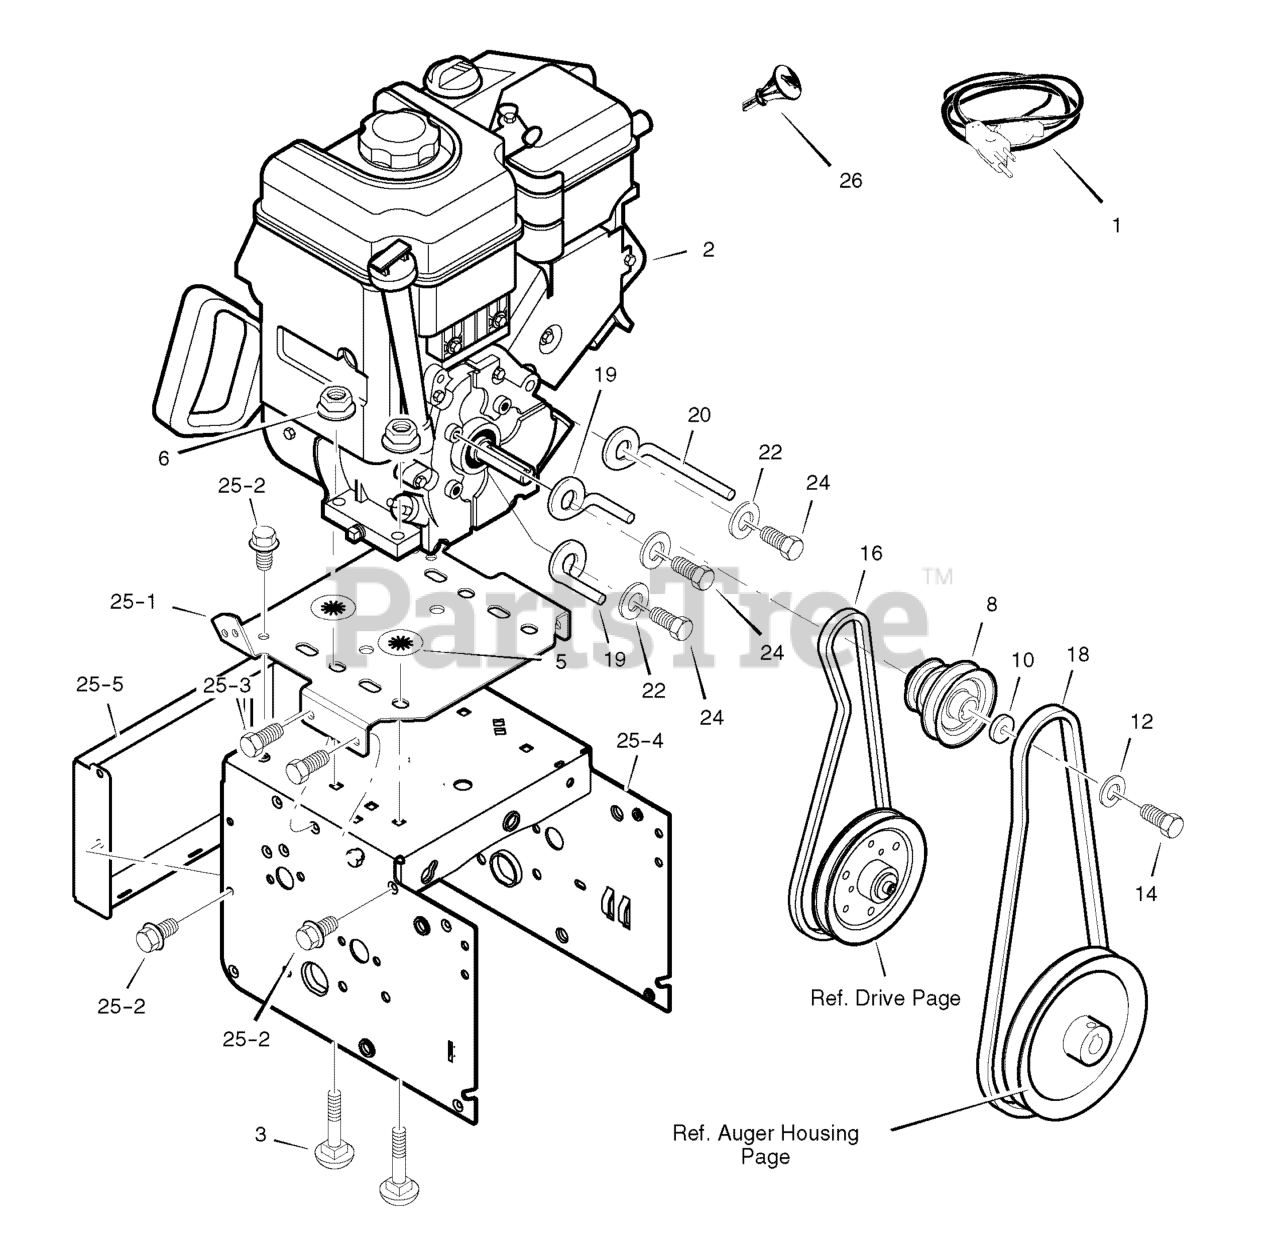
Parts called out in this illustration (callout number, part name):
1	CORD, Electric, 10FT. 110V
2	ENGINE
3	BOLT, CARRIAGE 5/16-18
5	RETAINER, PUSH
6	NUT, HEX 5/16-18
8	PULLEY, ENGINE
12	WASHER .38ID
14	SCREW, 3/8-24 X 1.00
16	BELT, HYDRO DRIVE
18	BELT, AUGER V 4L
19	GUIDE, BELT
20	GUIDE, BELT
22	WASHER, SPTLK 0.31 X 0.58 X 0.08
24	SCREW, 5/16-24 x 0.75
25	FRAME ASSEMBLY
25-1	PLATE, ENGINE MOUNT
25-2	SCREW, TAP 1/4-20 X 0.63
25-3	SCREW, TAP 5/16-18 X 0.50
25-4	FRAME, MOTOR BOX
25-5	PANEL, BACK - HYDRO
26	KEY, ENGINE
